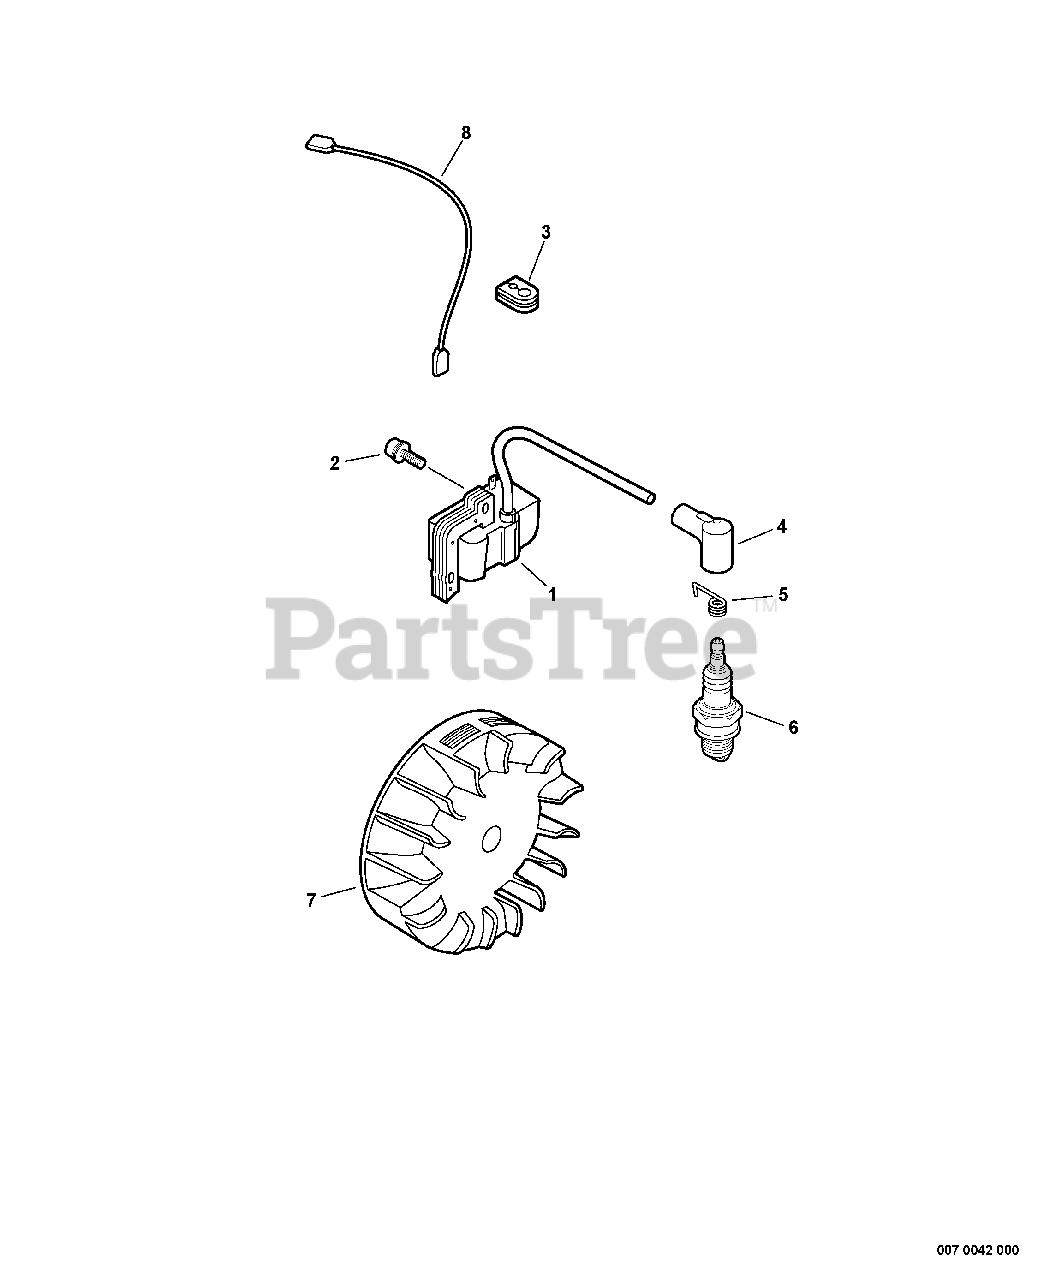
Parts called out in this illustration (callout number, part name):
1	COIL, IGNITION
2	SCREW - 4X22
4	CAP, SPARK PLUG
5	TERMINAL, SPARK PLUG CAP
6	SPARK PLUG -- BPM-7A
7	FLYWHEEL
8	LEAD - IGNITION
